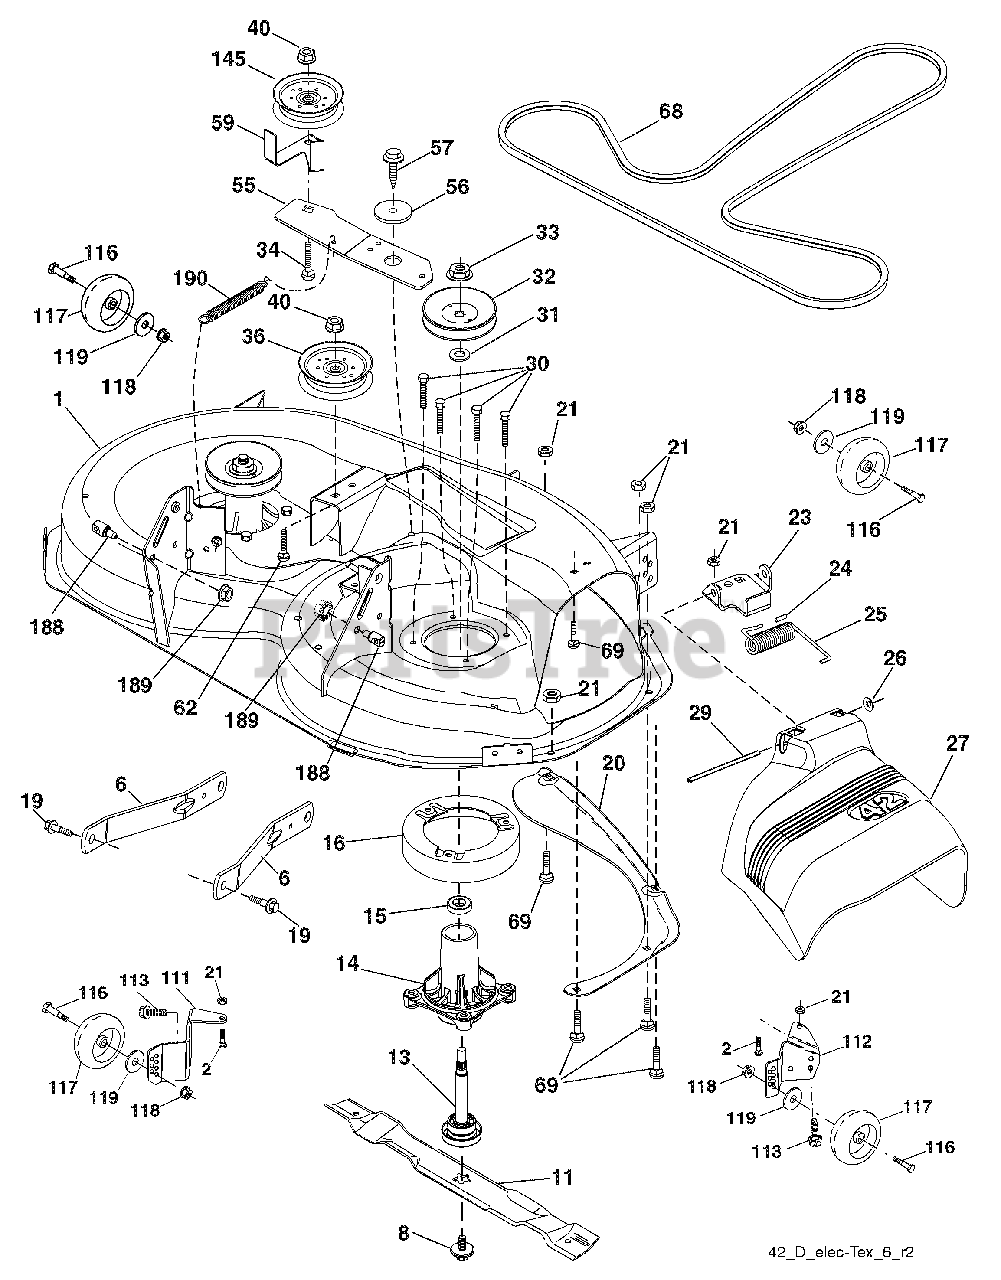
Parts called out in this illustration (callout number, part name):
1	Mower Housing
2	Bolt, Rdhd.5QNK 5/16-18 unc x 3/4
6	Arm Suspension
8	Bolt/Washer Asm 7/16-20 unf
11	Blade Mower
11	Blade, 42", Mulching Standard
11	Blade, 42", Mulching PREMIUM
13	Shaft Assembly, Mandrel
14	Housing, Mandrel
15	Bearing, Ball, Mandrel
16	Stripper Mandrel
19	Bolt, Shoulder
20	Baffle Vortex
21	Nut
23	Bracket, Deflector
24	Cap, Sleeve
25	Spring, Torsion, Deflector
27	Shield, Deflector
29	Rod, Hinge
30	Screw Thdrol Rolling Wsh Hd
31	Washer, Spacer
32	Pulley, Mandrel
33	Nut, Toplock, Flanged
34	Bolt Carr Sh. 3/8-16 x1-1/2 Gr. 5
36	Pulley, Idler, Flat
40	Nut, Lock Flg. 3/8-16 unc
55	Arm, Idler
56	Spacer, Retainer
57	Screw Hexwsh Thd 3/8-16 x 1
59	Guard, Tuv Idler
62	Bolt 3/8 - 16 unc x 2
69	Bolt
111	Bracket Wheel Gauge LH
112	Bracket Wheel Gauge RH
113	Screw 5/16-18
116	Bolt, Shoulder
117	Wheel, Gauge
118	Nut Centerlock 3/8 - 16 unc
119	Washer 3/8 x 7/8 x 14 Ga.
145	Pulley Idler
188	Stud Fastener
189	Nut Lock Hex Flange
190	Spring Mower Drive
190	Mandrel Assembly
190	Replacement Mower, Complete
